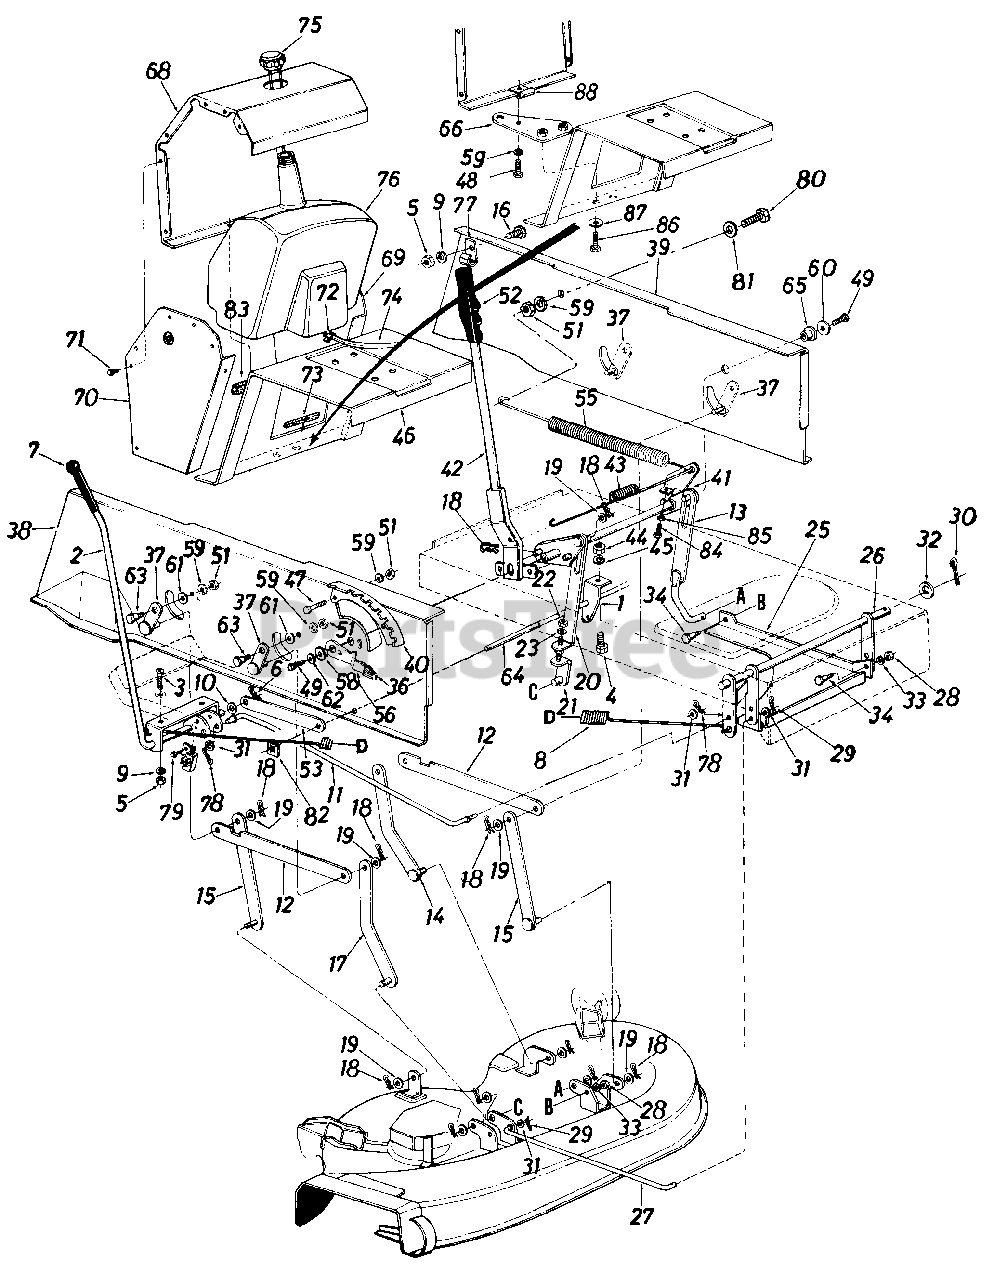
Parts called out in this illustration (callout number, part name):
1	Spring Hanger Bracket
2	Deck Engagement Lever Ass'y.
3	Truss Mach. Scr. 5/16-18 x .75" Lg.
4	Hex Bolt 1/4-20 x .62" Lg.
5	Hex Nut 5/16-18 Thd.
6	Cotter Pin 3/32" Dia. x 1.00" Lg.
8	Ext. Spring .99" O.D. x 22" Lg.
9	L-Wash. 5/16" I.D.
10	Fl-Wash. .510" I.D. x 1.0" 0. D.
11	Drive Deck Control Rod
12	Connecting Rod 3/16 x 1 x 1 2.5
13	Deck Lift Link Ass'y.
14	Deck Hanger Link Ass'y.-Rear L.H.
15	Deck Hanger Link Ass'y.
16	Hex Bolt 5/16-18 x .75" Lg.
17	Deck Hanger Link Ass'y.- Front R.H.
18	Inter. Cotter Pin 1/2" Dia.
19	Fl-Wash. .531 I.D. x .93" O.D.
20	Adj. Link Deck Lifting
21	Adj. Lower Link Ass'y.
22	Hex Jam Nut 3/8-24 Thd.
23	L-Wash. 3/8" I.D.
25	Diagonal Brace
26	Stabilizer Shaft Ass'y.
27	Stabilizer Rod
28	Hex Nut 3/8-16 Thd.
29	Cotter Pin 3/32" Dia. x 1.0" Lg.
30	Cotter Pin 1/8" Dia. x 1.25" Lg.*
31	Fl-Wash. .385" I.D. x .620" O.D.
32	Fl-Wash. .635" I.D. x 1.12" O.D.
33	L-Wash. 3/8" I.D.
34	Shoulder Bolt 3/8-16
36	Knob-Height Adj.
37	Pivot Link Ass'y.
38	Side Panel Upper Frame-R.H.
39	Side Panel Upper Frame-L.H.
40	Index Brkt.
41	Lift Shaft Ass'y.
42	Lift Handle Brkt. Ass'y.
43	Ext. Spring .56" I.D. x 32 Coils
44	Hex Nut 1/4-20 Thd.*
45	L-Wash. 1/4" I.D.*
46	Hitch Plate
47	Hex Bolt 5/16-18 x .75" Lg.*
48	Hex Bolt 5/16-18 x 1.00" Lg. (Grade 5)
49	Hex Wash. TT-Tap Scr. 5/16-18 x .62" Lg.
51	Hex Nut 5/16-18 Thd.*
52	Grip
53	Link 1.0" x 7.5" x .19
55	Ext. Spring .99" Dia. x 11.00" Lg.
56	Deck Lift-Down Stop
58	Flange Brg. .630" I.D.
59	L-Wash. 5/16" I.D.*
60	Fl-Wash. .344" I.D. x 1.125" O.D. x .125
61	Fl-Wash. .344" I.D. x .62" O.D. x .063
62	Fl-Wash. .344" I.D. x 1.125" O.D.
63	Shld. Bolt .437" Dia. x .180
64	Running Board Rod
65	Flange Brg. .632" I.D.
66	Hitch Bar
68	Gas Tank Housing
69	Side Panel-L.H.-Gas Tank
70	Side Panel-R.H.-Gas Tank
71	Truss Mach. B-Tapp Scr. #10 x .50" Lg.
72	Hose Clamp-.406" Dia.
73	Trim Strip-5" Lg.
74	Gas Line-44" Lg.
75	Gas Tank Cap
76	Gas Tank
77	Hose Clamp
78	Cotter Pin 3/32" Dia. x .75" Lg.
79	Hex Wash. Hd. Tap Scr. 1/4 x.50" Lg.
80	Hex Bolt 5/16-18 x 1.50" Lg.*
81	Fl-Wash. .344" I.D. x .875" O.D.
82	Speed Nut .5" Dia. Stud
83	Foam Strip 3/8" x 1-1/8" x 11/2" Lg.
84	Hex Tap Scr. 5/16-18 x 1'
85	Hex Jam Nut 5/16-18 Thd.
86	Self-Tap Scr. 3/4" Lg.
87	Bell-Wash. 3/8" I.D.
88	Speed Nut
